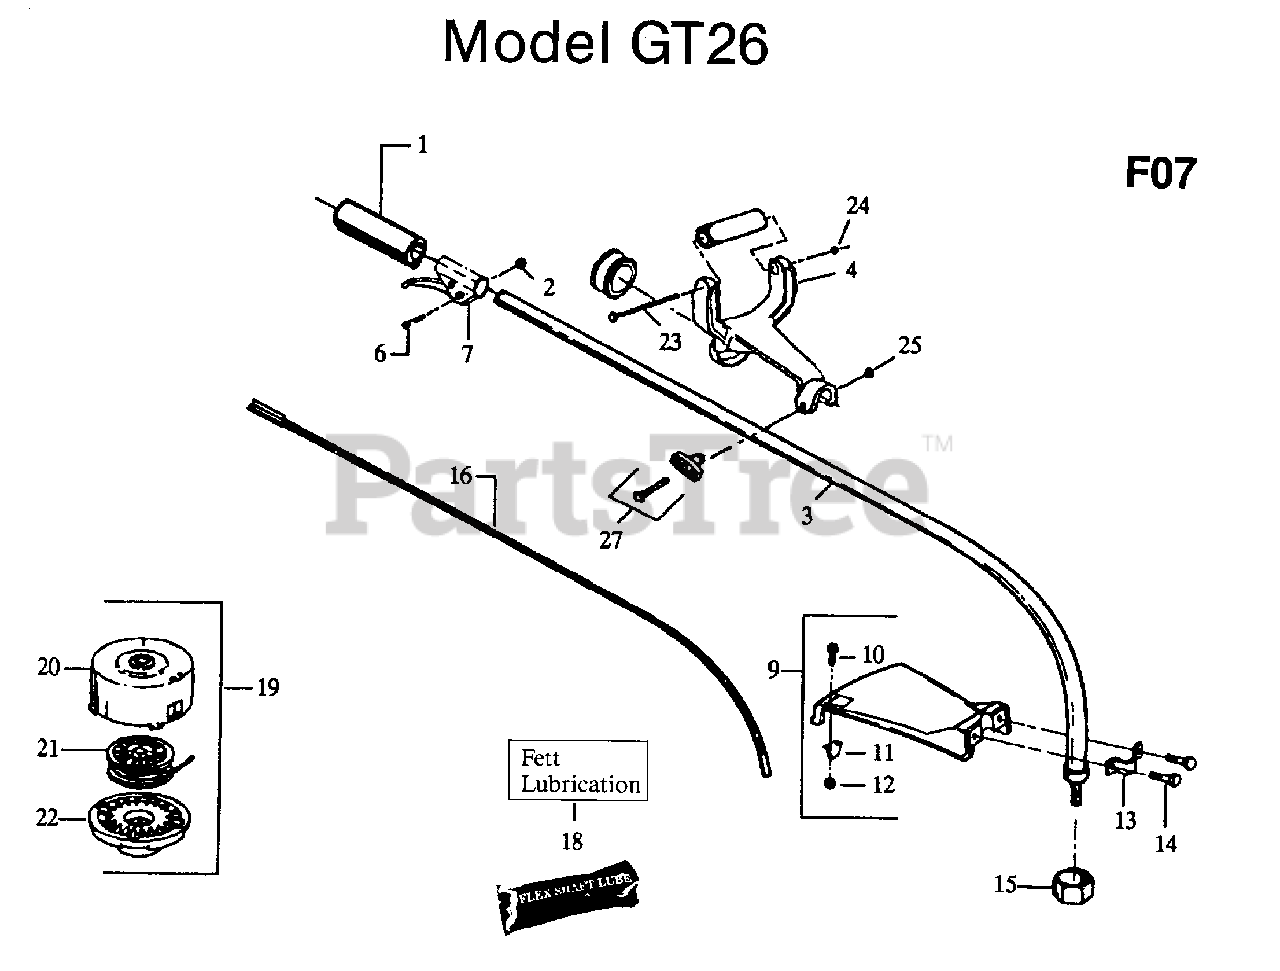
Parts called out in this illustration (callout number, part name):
1	GRIP-DRIVE SHAFT
2	LOCKNUT-HEX 10-24
3	ASSY-DRIVE SHAFT HSG
4	ASS'Y-HANDLE ANTIVIB
6	SCREW-10-24 X 1" (UNC)
7	ASSY-THROTTLE HOUSING
9	SHIELD
11	LIMITER-LINE
12	LOCKNUT-(10-24)
13	BRACKET-SHIELD
14	SCREW-1/4-10X1-1/8 HEX
16	SHAFT-FLEX (48")
18	GREASE-1/2 FL. OZ.
20	ASSY-HUB, SHAFT & BAL A NLA
23	SCREW-12-24 X 4-11/16 P
24	NUT-12-24 (HEX)
27	KIT "T" HANDLE
